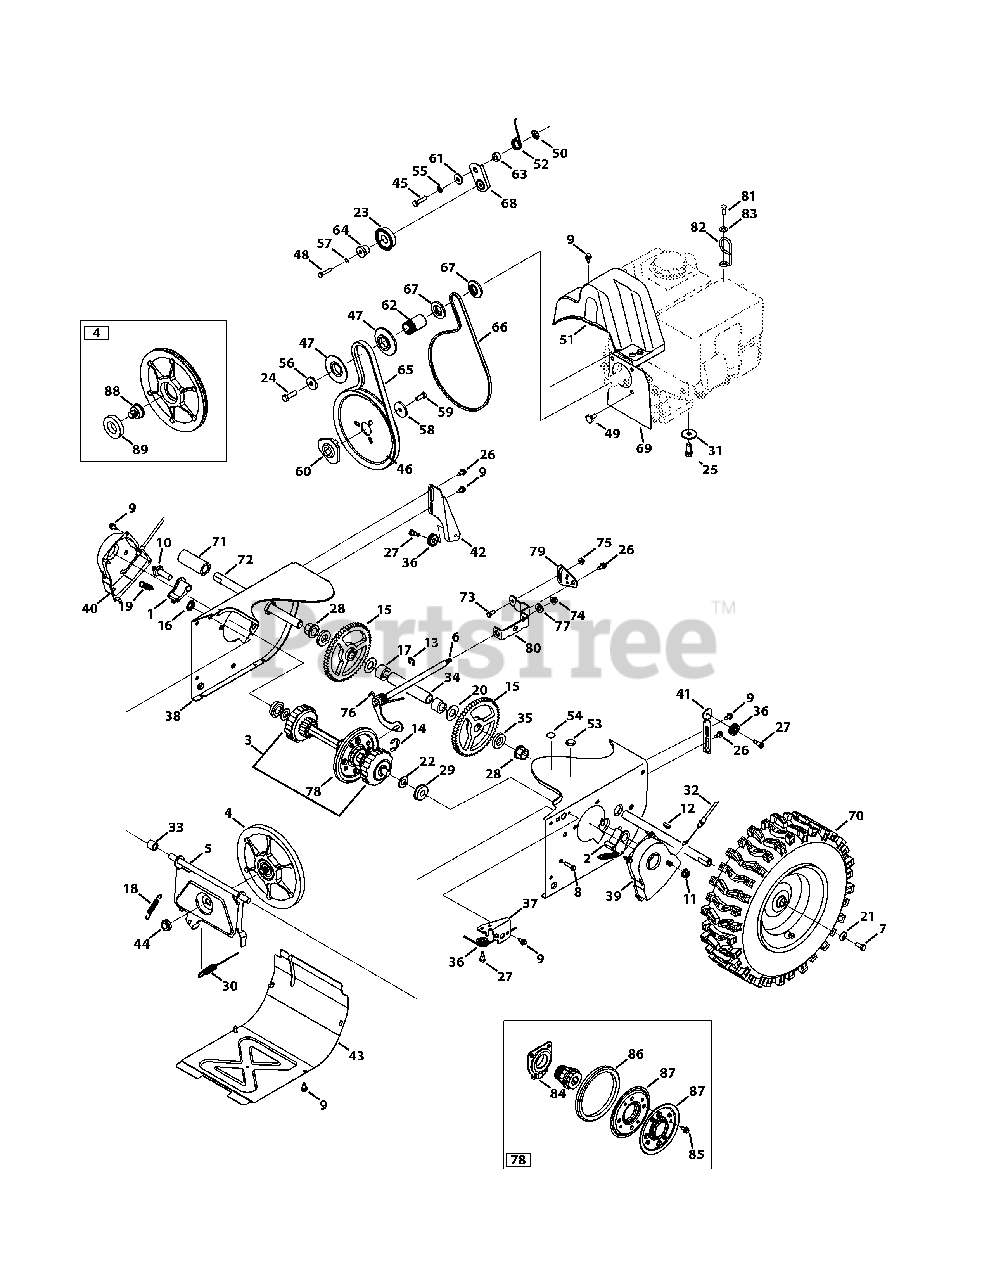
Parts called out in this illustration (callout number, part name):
1	Dogg Assembly, RH
2	Dogg Assembly, LH
3	Drive Shaft Assembly
4	Friction Wheel Disc Assembly
5	Friction Wheel Support Bracket
6	Rod Shift Assembly
7	Hex Head Screw, 5/16-24 x .750
8	Screw, 1/4-20 x 1.000
9	Screw, 1/4-20 x .625
10	Actuator Shaft
11	Nut, Flangelock, 3/8-16
12	Hi-Pro Key, 3/16 x 3/4 DIA
14	Retainer Ring
16	Nut, Speed, .500
17	Spacer, .76 x .75
18	Extension Spring, .380 x 2.500
19	Extension Spring, .500 x 1.71
20	Washer, Flat, .76 x 1.49
21	Washer, Bell, .340 x .872
22	Washer, Flat, .58 x 1.125
23	Idler Pulley Assembly
24	Hex Head Screw, 3/8-24 x 1.25
25	Taptite Sems Screw, 3/8-16 x 1.000
26	Screw, Shoulder, .368 x .113 x 1/4-20
27	Screw, Shoulder, .340 x .335 x 1/4-28
28	Hex Flange Bearing, .75 ID
29	Ball Bearing, .5625 x 1.375 x .4375
30	Drive Clutch Cable
31	Washer, Flat, .38 x 1.38
32	Steering Cable
33	Spacer, .508 x .75
34	Axle Support Tube
35	Spacer, Axle
36	Cable Roller
37	Auger Cable Guide Bracket
41	Auger Clutch Cable Guide Bracket
42	Drive Clutch Cable Guide Bracket
44	Nut, Flange, 5/8-18
45	Hex Head Screw, 5/16-24 x 1.25
46	Auger Pulley, 8.1 x .5
47	Pulley, Half, 2.600
48	Taptite Screw, 1/4-20 x 1.250
49	Shoulder Screw, .500 x .145
50	Nut, Push-On, .25 Dia.
51	Belt Cover, (528 SW/SWE & 526 SWE)
51	Belt Cover (524 SWE)
52	Spring, Torsion, .850 x .333
53	Plug, 3/8 ID
54	Plug, 1/2 ID
55	Washer, Lock, 5/16
56	Washer, Flat, .406 x 1.25
57	Washer, Lock, 1/4
58	Washer, Flat, .34 x 1.50
59	Hex Head Screw, 5/16-24 x .875
60	Pulley Adapter, .75 DIA
61	Spacer, Shoulder, .3175 x .500
62	Spacer, .875 x 1.185
63	Spacer, .340 x .750
64	Spacer, Shoulder, .260 x .785
65	Belt, .500 x 37 (528 SW/SWE & 526 SWE)
65	Belt, .500 x 35.06 (524 SWE)
66	Belt, 3/8 x 35.68 (528 SW/SWE & 526 SWE)
66	V Belt, 3/8 x 34.4 (524 SWE)
67	Pulley, Half, 3/8 x 1.7160
68	Drive Idler Bracket
69	Cover Plate (528 SW/SWE & 526 SWE)
69	Cover Plate (524 SWE)
70	Wheel, LH (528 SW/SWE)
70	Wheel, RH (528 SW/SWE)
70	Wheel, LH (526 SWE)
70	Wheel, RH (526 SWE)
70	Wheel, LH (524 SWE)
70	Wheel, RH (524 SWE)
71	Spacer, 1.25 x .75 x 3.00
72	Axle, .75 x 11.12
73	Hex Head Screw, 1/4-20 x .620
74	Nut, Flange Lock, 5/16-18
75	Nut, Flange Lock, 1/4-20
76	Spring, Torsion, .750 x .968
77	Washer, Flat, .469 x .875 x .105
78	Friction Wheel Assembly
79	Speed Selector Pivot Bracket
80	Speed Selector Shift Bracket
81	Hex Head Screw, 1.25 x 20
82	Cable Guide (524 SWE)
82	Cable Guide (526 SWE, 528 SW/SWE)
83	Washer, Flat, .330 x .630
84	Bearing Assembly, Friction Wheel
85	Screw, 1/4-14 x .625
86	Friction Wheel, 5.5 OD
87	Friction Wheel Plate
88	Friction Pin, Disc Bearing
89	Ball Bearing, 30 x 55 x 13
